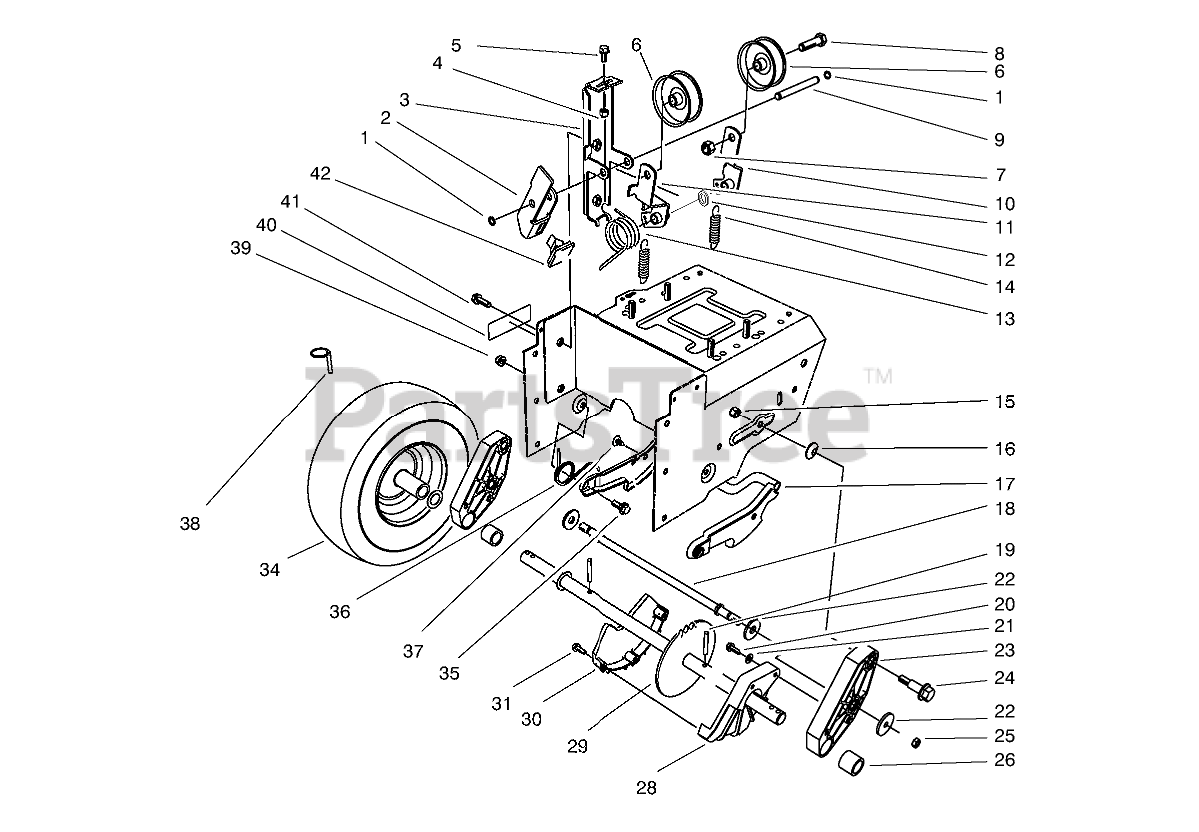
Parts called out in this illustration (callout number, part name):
1	RING-RETAINING
2	ARM-BRAKE
3	IDLER ARM BRACKET ASM
4	NUT-LOCK, NI
5	SCREW-HHF
6	PULLEY-IDLER
7	NUT-LOCK, NI
8	SCREW-HH
9	PIN-IDLER
10	TRACTION IDLER ARM ASM
11	IMPELLER IDLER ARM ASM
12	WASHER-FLAT
13	SPRING-TORSION
14	SPRING-EXTENSION
15	NUT-LOCK, NI
16	WASHER-SPRING
17	Latch-Arm
18	ROD-LATCH
19	PIN-ROLL, SLOTTED
20	SCREW-HWH
21	WASHER-FLAT
22	WASHER-SUPPORT
23	Pivot Arm Assembly (Incl. Ref. # 26)
24	BOLT-SHOULDER
25	NUT-LOCK, NI
26	BUSHING-AXLE
27	WASHER-THRUST
28	GUARD-CHAIN, LH
29	AXLE ASM
30	GUARD-CHAIN, RH
31	SCREW-PPH
34	Wheel And Tire ASM
35	SCREW-SHOULDER
36	SPRING-LATCH, TORSION
37	FASTENER-PANEL
38	PIN-LYNCH
39	NUT-LOCK, NI
40	DECAL-WARNING
41	SCREW-HHF
42	PAD-BRAKE
